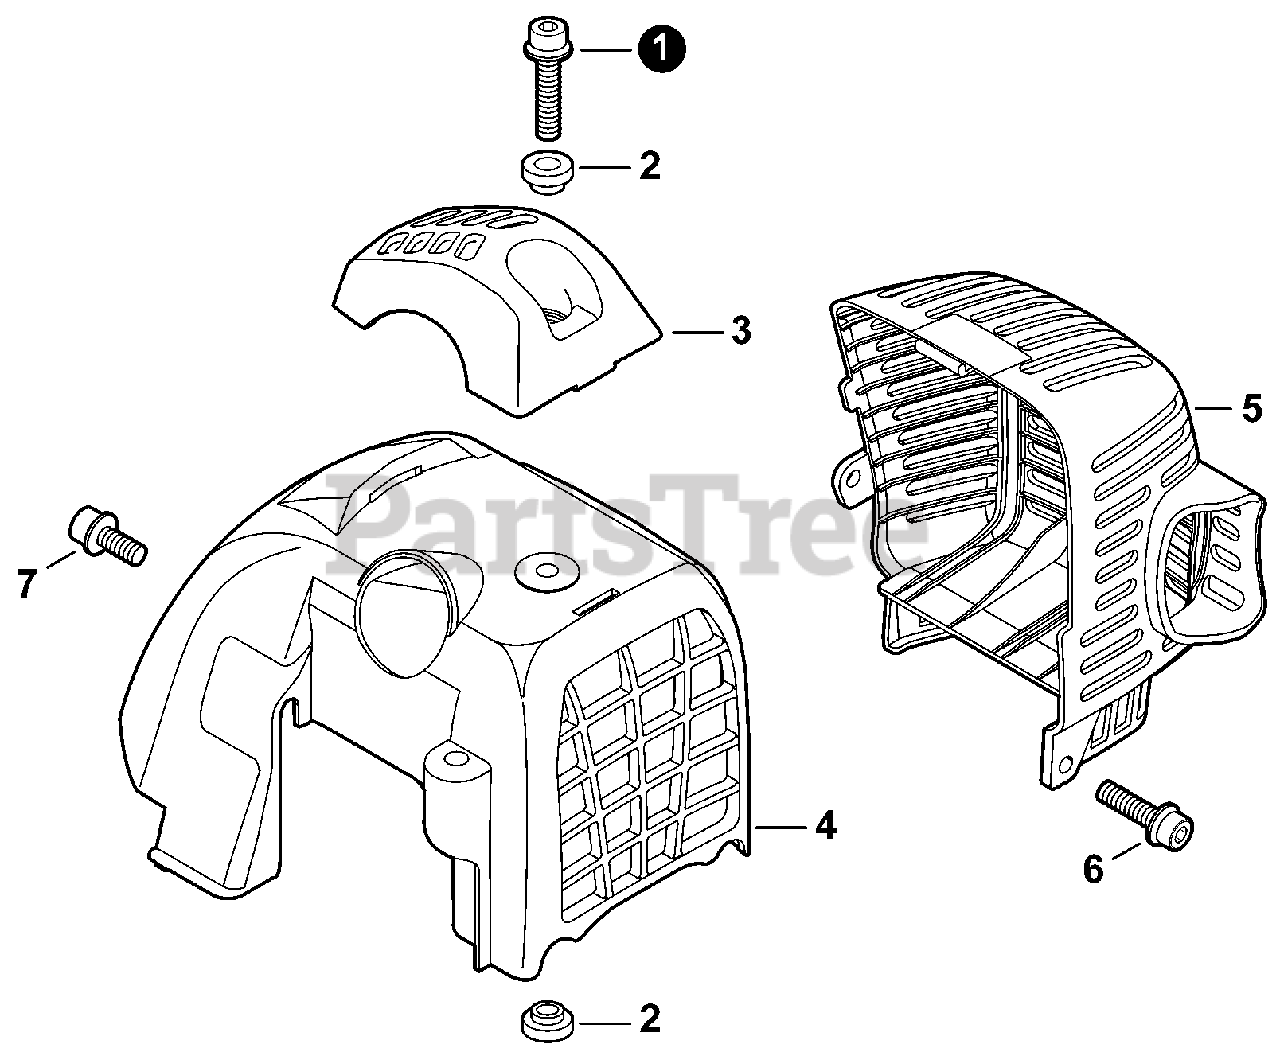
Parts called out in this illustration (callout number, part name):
1	BOLT 5×20
2	COLLAR 5
3	GUARD, TOP
4	COVER, ENGINE
5	COVER, MUFFLER
6	SCREW 5×16
7	SCREW 5×10
